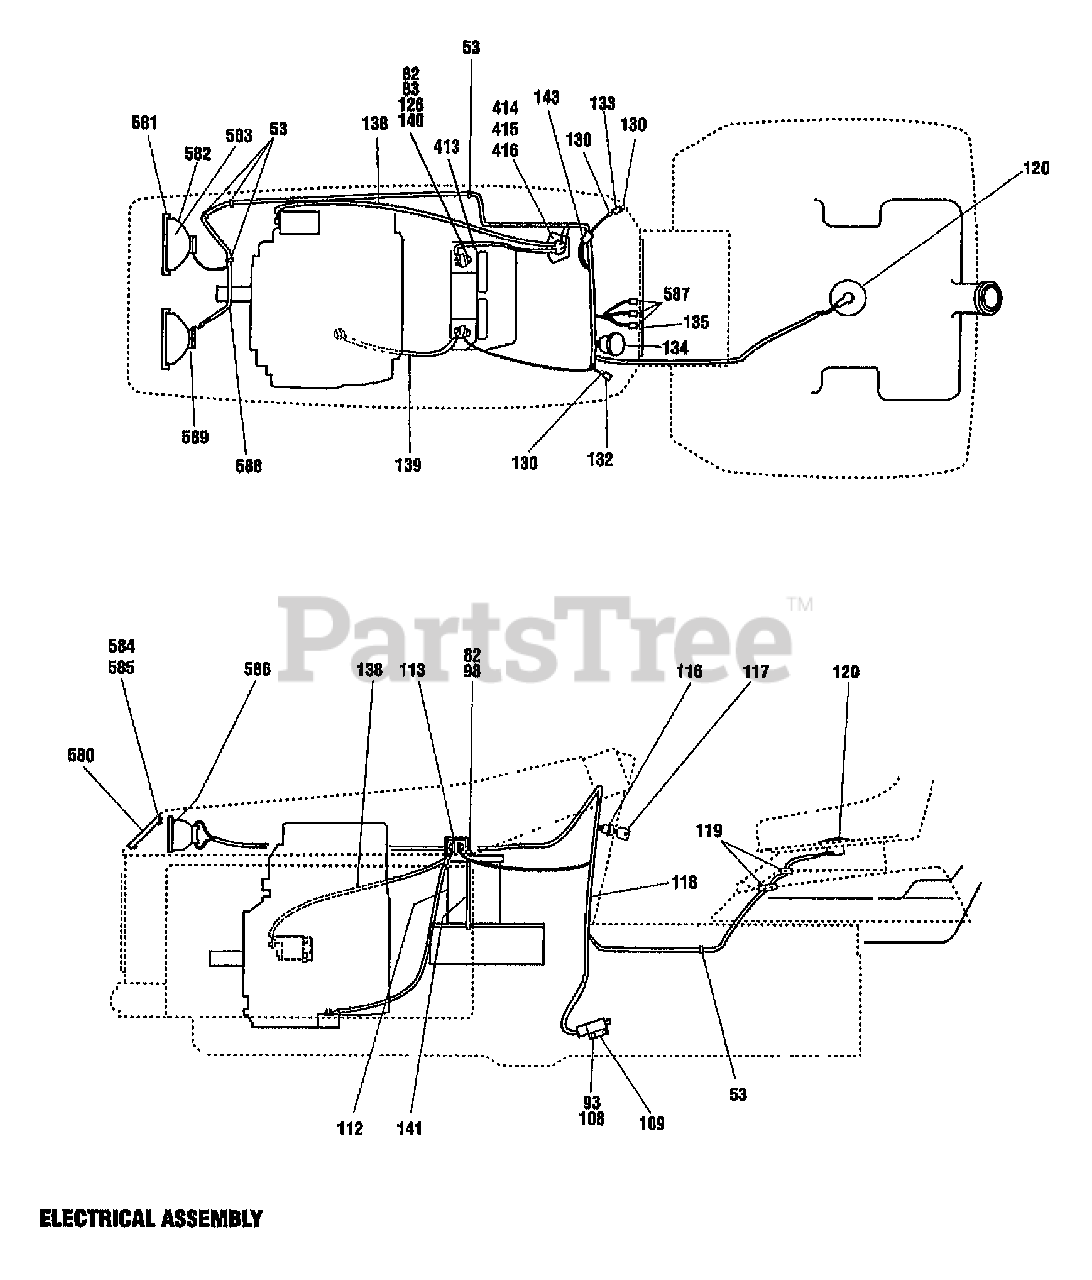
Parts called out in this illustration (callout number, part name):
53	CABLE TIE
82	WASHER-FLAT 1/4 SAE
83	WASHER-LK .25 ZP
93	NUT W/LKWASHER 10-24 ZP
98	NUT-HT LK 1/4-20
108	SCR-TRUSS #10-24 X 5/8
109	SWITCH
112	BATTERY
113	BATTERY-HOLDDOWN
116	SWITCH-IGNITION
117	KEY-IGNITION
118	HARNESS-MAIN
119	GROMMET
120	SWITCH-SEAT
120	SWITCH
126	NUT-HEX 1/4-20 ZP
130	SCR-FHP #6-32X.50 ZP
132	SWITCH-LIGHT
133	SWITCH-PTO
134	METER-HOUR
135	LENSE
138	CABLE-POSITIVE
139	CABLE (-)
140	SCR-HH 1/4-20X.75 G5 ZP
141	BOLT-HOOK
143	SENSOR-VOLTAGE
413	CABLE-BATTERY (+)
414	SOLENOID
415	SCR 1/4-20X.5 FL SELF TAP
416	BOOT-SOLENOID
580	LENSE
581	RETAINER
582	ASSM-LIGHT
583	LIGHTBULB
584	SCR-EXHAUST DEFLECTOR
585	WASHER-.44X.189X.05
586	GASKET
587	BULB (MFG NO. GE 73)
588	HARNESS-HEADLIGHT
589	SOCKET
